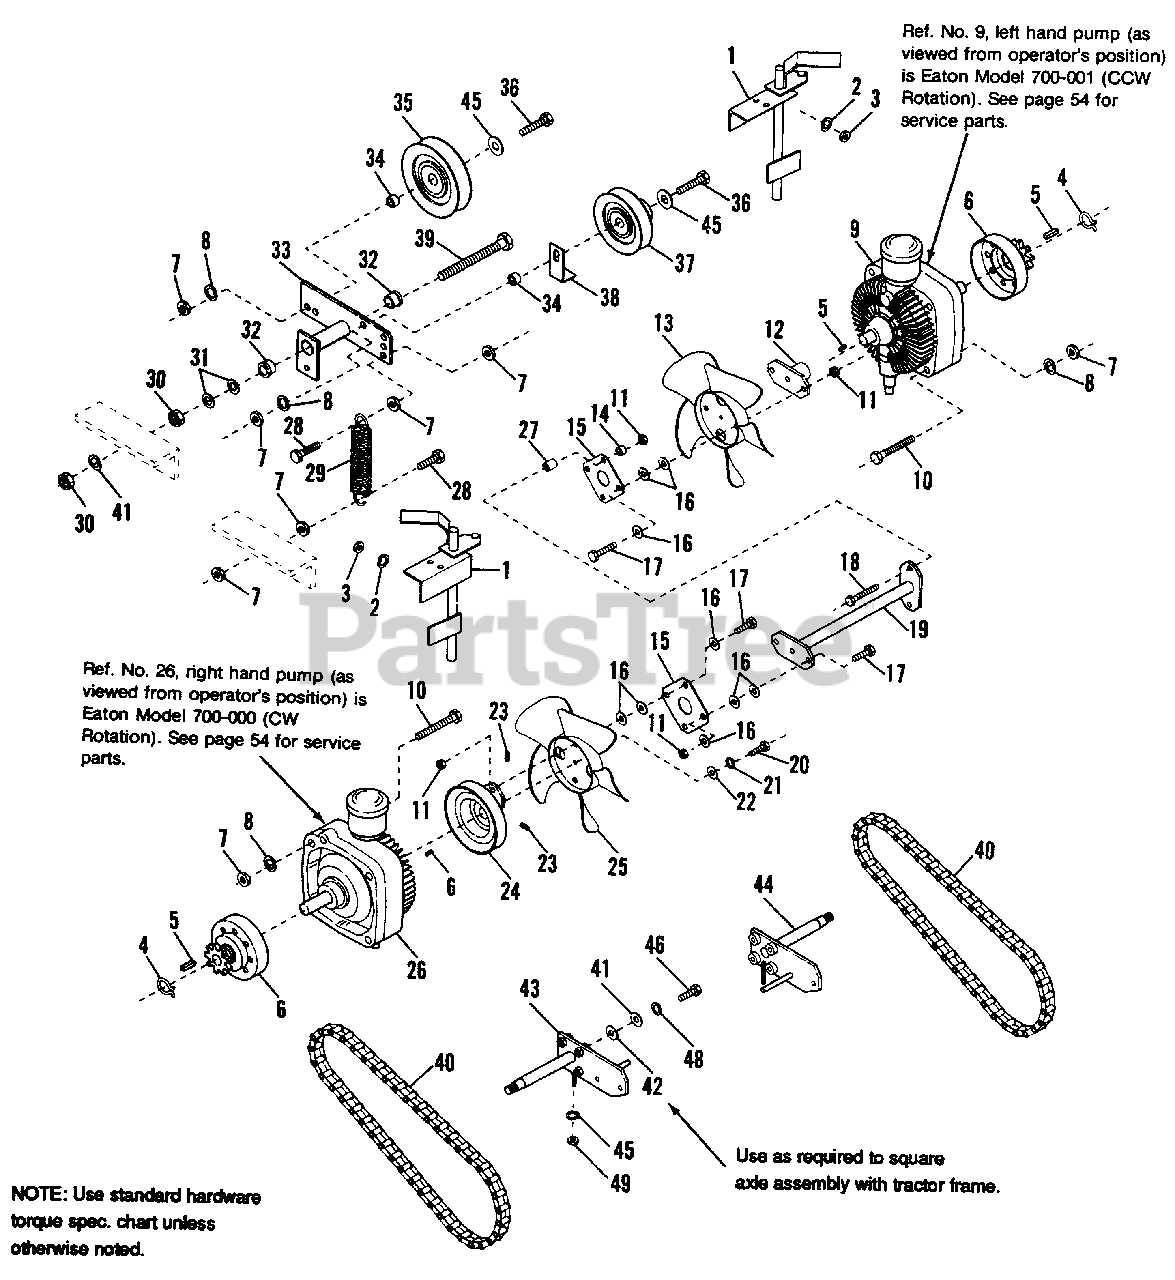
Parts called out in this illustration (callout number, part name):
1	TOW CONTROL ASSY.
2	LOCKWASHER, Spring 5/16
3	NUT, Hex 5/16-18
4	RING, Retaining, External
5	KEY, Hi-Pro 1/8 x 1/2
6	SPROCKET AND DRUM ASSY.
7	NUT, Hex 3/8-16
8	LOCKWASHER, Spring 3/8
9	HYDROSTATIC TRANSMISSION, Left Hand (Model 700-001)
10	CAPSCREW, Hex 3/8-16 x 3
11	LOCKNUT, Hex 5/16-18
12	HUB ASSY.
13	FAN ASSY., Left Hand
14	SPACER, Short
16	WASHER, Plain
16	AXLE PLATE ASSY., Left Hand (1691842, 1691844, 1691846)
17	CAPSCREW, Hex 5/16-18 x 1
18	CAPSCREW, Hex 5/16-18 x 1-3/4
19	SHAFT ASSY.
20	CAPSCREW, Hex 1/4-20 x 3/4
21	LOCKWASHER, Spring 1/4
22	WASHER, Plain
23	SETSCREW 1/4-28 x 1/2
24	V-PULLEY ASSY.
25	FAN ASSY., Right Hand
26	HYDROSTATIC TRANSMISSION, Right Hand (Model 700-000)
27	SPACER, Long
28	CAPSCREW, Hex 3/8-16 x 1-1/2
29	SPRING, Extension
30	NUT, Jam, Hex 1/2-13
31	WASHER, Plain
32	BUSHING, Flanged
33	IDLER ARM ASSY.
35	V-PULLEY, Idler
36	CAPSCREW, Hex 3/8-16 x 2
37	V-PULLEY, Idler
38	RETAINER, Belt
39	CAPSCREW, Hex 1/2-13 x 5
40	CHAIN, Drive
41	LOCKWASHER, Spring 1/2
42	WASHER, Plain
43	AXLE PLATE ASSY., Right Hand (1691841, 1691843, 1691845)
43	AXLE PLATE ASSY., Right Hand (1691842, 1691844, 1691846)
44	AXLE PLATE ASSY., Left Hand (1691841, 1691843, 1691845)
45	WASHER, Plain
46	CAPSCREW, Hex 7/16-20 x 2
47	WASHER, Plain
48	LOCKWASHER, Spring 7/16
49	NUT, Hex ESNA Lock 3/8-16
